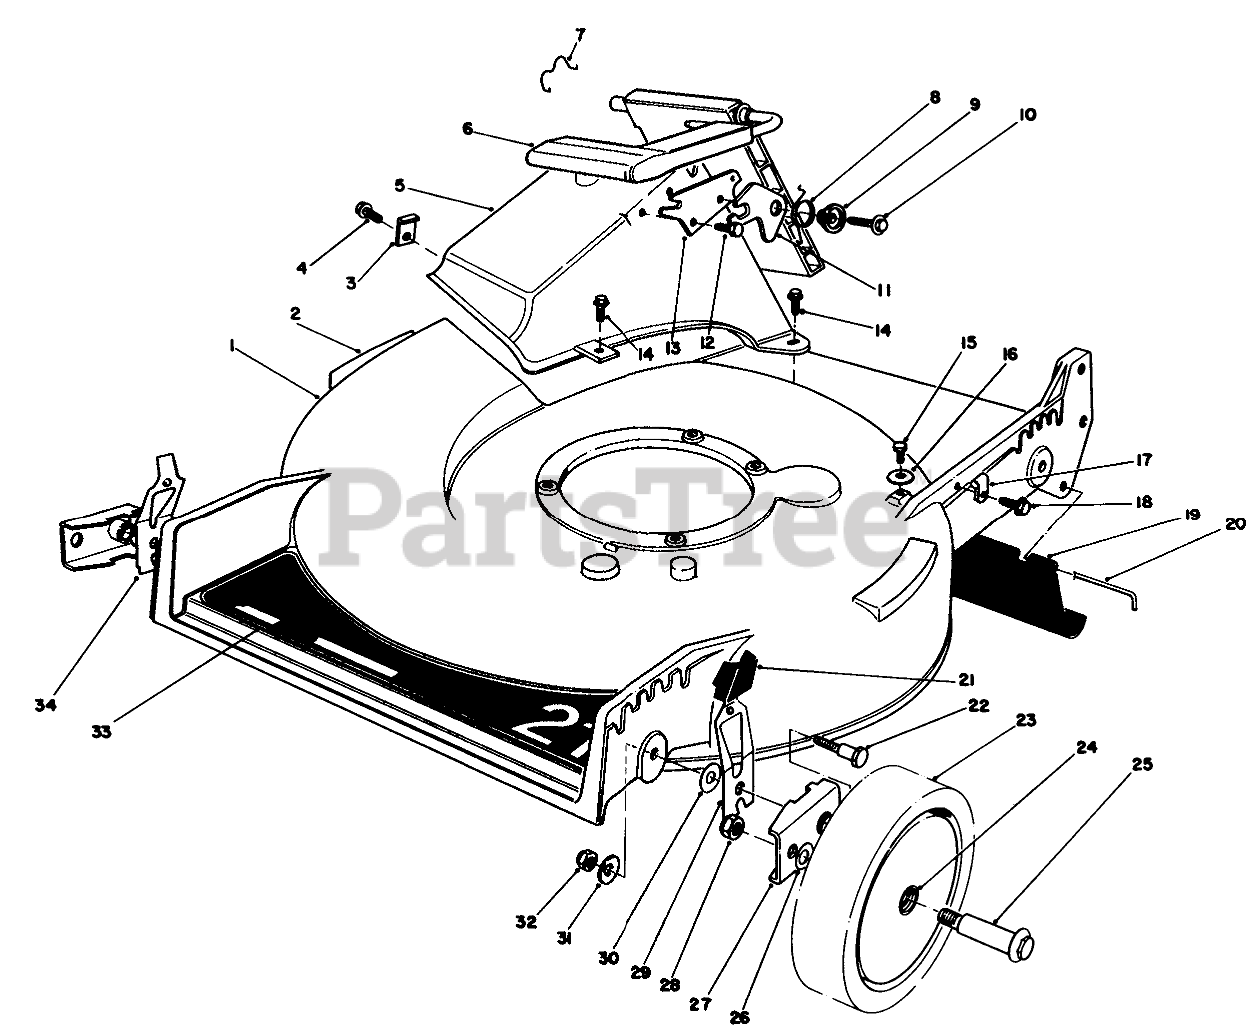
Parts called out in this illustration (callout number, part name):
1	Housing (Incl. Ref. #2)
2	DECAL-DANGER
3	TUNNEL CLIP
4	SCREW
5	Tunnel Discharge
6	Discharge Door Assembly
7	DOOR RET SPRING
8	TORSION SPRING
9	DOOR SPACER
10	SCREW-HWH
11	SAFETY LATCH
12	SCREW-PLASTITE
13	DOOR LATCH PLATE
14	SCREW-HWH
15	SCREW-HWHTF
16	WASHER-FLAT
17	CLAMP-CABLE
18	SCREW
19	SHIELD-TRAILING
20	ROD-SHIELD
21	KNOB-ARM
22	PIVOT SCREW
23	Wheel & Tire Assembly (Incl. Ref. #24)
24	BUSHING
25	WHEEL BOLT
26	WASHER
27	HP PIVOT ARM ASM
28	NUT-LOCK
29	L. HP SPRING ARM ASM
30	WASHER-PIVOT
31	WASHER-BELLEVILLE
32	NUT-LOCK, NI
33	DECK DECAL
34	R HP SPRING ARM ASM
